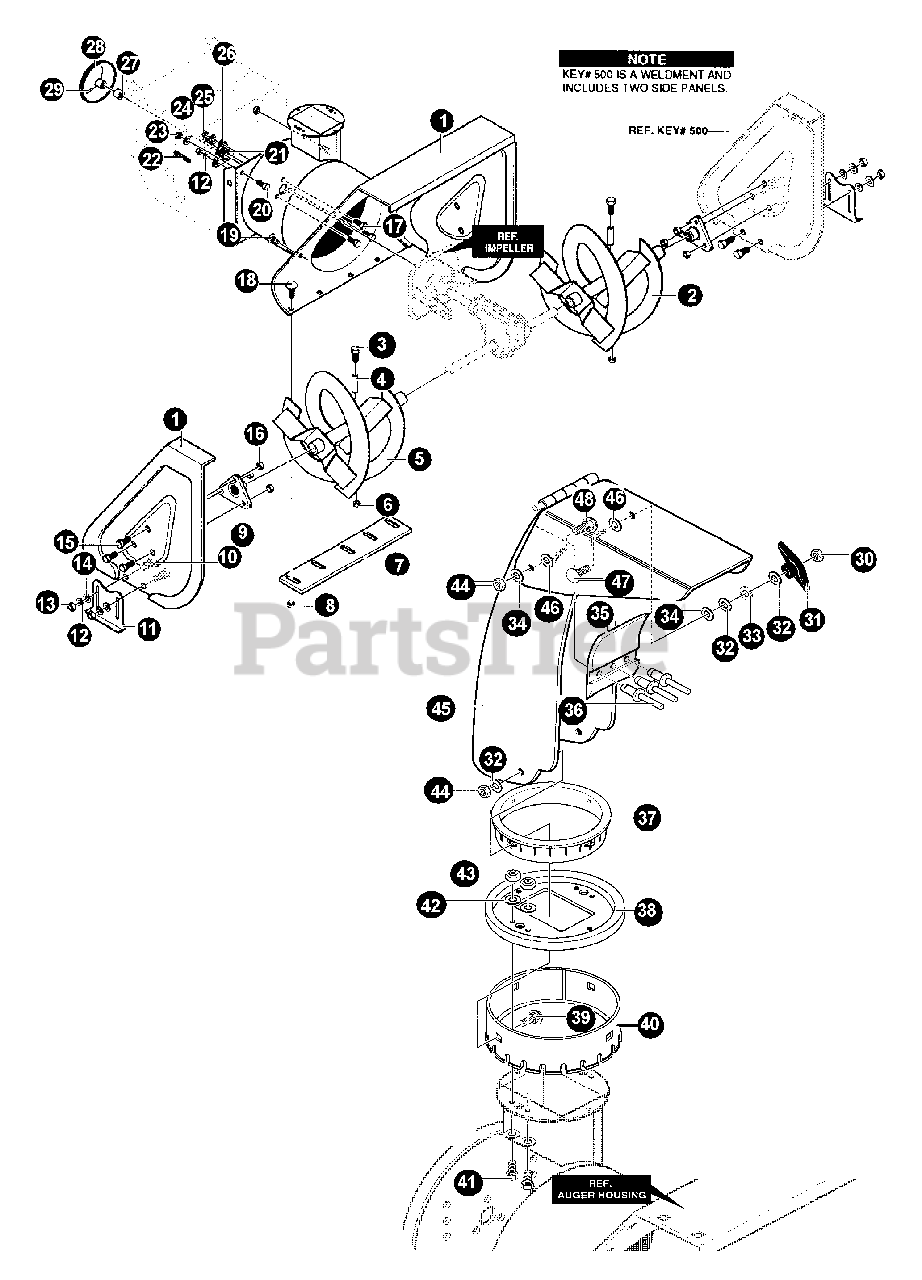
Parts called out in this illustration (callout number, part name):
1	AUGER INTAKE ASSY
2	AUGER ASSY - RIGHT
3	SCREW - 1/4-20 X 1-3/4"
4	SPACER, SLEEVE .250X.47X.20
5	AUGER ASSY - LEFT
6	NUT - 1/4-20
7	BLADE, SCRAPER
8	LOCKNUT - 1/4-20
9	BEARING, FLANGE
10	BOLT - 5/16-18 X 3/4"
11	SKID, HEIGHT
12	LOCKWASHER
13	NUT - 5/16-18
14	WASHER
15	SCREW - 5/16-18 X 3/4"
16	NUT - 5/16-18
17	SCREW - 5/16-18 X 3/4"
18	BOT, 1/4-20X.75 CARR
19	FASTENER, RATCHET
20	SCREW - 3/8-16 X 3/4"
21	BEARING, BALL
22	KEY, SQUARE .18SQX88LG
23	NUT - 3/8-16
24	LOCKWASHER
25	NUT - 5/16-18
26	RETAINER, BEARING
27	SPACER, SLEEVE .675X1.00X.53
28	PULLEY, V4L6.22X.67
29	SCREW - 5/16-28 X 5/8"
30	NUT - 5/16-18
31	KNOB, T 2 BLADE W/5/16-18 NUT
32	WASHER
33	LOCKWASHER
34	WASHER - PLASTIC
35	FLAP, CHUTE INSERT
36	RIVET
37	RETAINER, RING INNER
38	COLLAR
39	BOLT, 5/16-18X1.00 CARRLN
40	RETAINER, RING OUTER
41	SCREW - 1/4-20
42	WASHER
43	NUT - 1/4-20
44	NUT - 5/16-18
45	CHOKE ASSY
46	WASHER - PLASTIC
47	BOLT - 5/16-18 X 1"
48	BOLT - 5/16-18 X 3/4"
